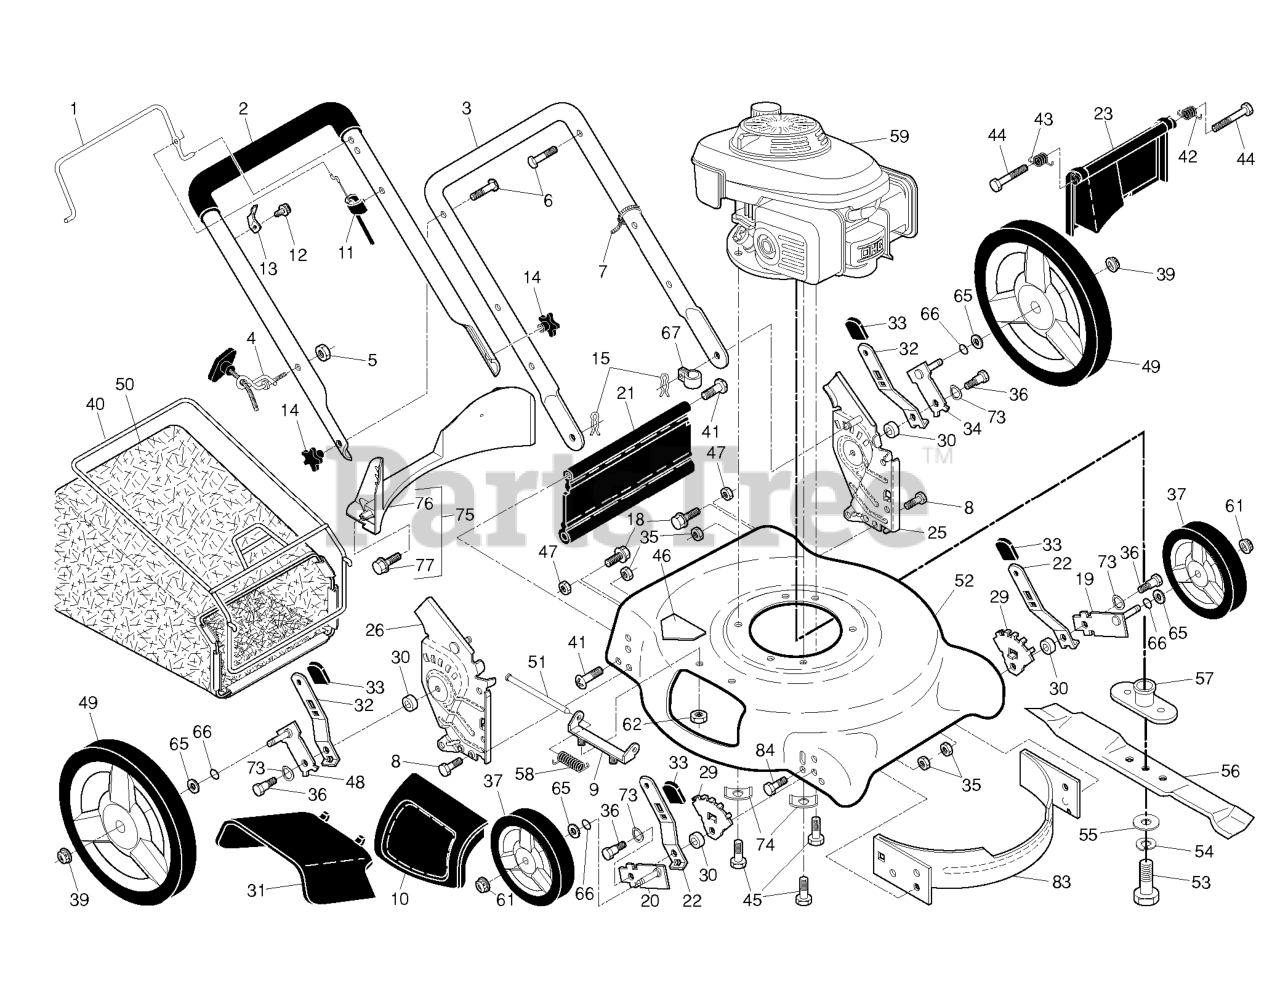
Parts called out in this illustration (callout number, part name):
1	BAIL.MZR.STD.ORANGE
2	UPPERHANDLE(INCLUDES FOAMGRIP)
3	HANDLE.LOWER.GREY
4	RB GUIDE.ROPE.STD.BLK.ZIN WSL
5	NUT
6	BOLT, HANDLE 5/16-18X1.75
7	TIE GUIDE
8	BOLT.FIN.HEX.5/16-18X3/4
9	BRACKET.ASM.HOUSING.EZ.MUL
10	RP DOOR.MULCH.21".REAR.PUSH.GR
11	CABLE.ENGINE.ZONE.CONTROL
13	BRACKET.UPSTOP.RT
14	KNOB.HANDLE.PLASTIC.STAR.BLACK
15	HAIRPIN COTTER
18	SCREW 1/4X20
19	AXLE ARM ASSY FRONT LH
20	AXLE ARM ASSY FRONT RH
21	RP_KIT.SKIRT.21 DOMED.W/LIP
22	SELECTOR SPRING, FRONT
23	REAR DOOR ASSY
25	RP BRKT.ASM.HAND.HW.21.LT.ORNG
26	RP BRKT.ASM.HAND.HW.21RT.ORNG
29	WHEEL ADJ BRACKET FRONT
30	SPACER.HEIGHT.ADJUSTER
31	DEFLECTOR.CLIPPING.21.GREY
32	SPRING.SEL.EXT.21.DOMED.12/14
34	AXLE ARM ASSY REAR LH
35	NUT.FLANGE.HEX.5/16X18.BLACK
36	SHOULDER BOLT 5/16-18
37	WHEEL & TIRES ASSY, FRONT
39	NUT.HEX.FLANGE.3/8-16.LOCKNUT
40	FRAME.BAG.21.REAR.DOMED.PUSH
41	HINGE SCREW
42	SPRING.LH.22.REAR.DOOR.EZ.EMPT
43	SPRING.RH.22.REAR.DOOR.EZ.
45	BOLT 3/8-16X1-1/8
46	DANGER DECAL
47	NUT.LOCK.5/16-18
48	AXLE ARM ASSY REAR RH
49	WHEEL ASSY
50	GBAG.2323247.SILVER
51	ROD.HINGE.COMBI-C
52	HOUSING.21.M/C.DOME.ORANGE
53	SCREW, HEX HD 3/8-24 X 1-3/8
54	LOCKWASHER
55	WASHER,HARDEN
56	BLADE.21.PUSH/RWGD/FWGD
57	ADAPTER.BLADE.W/KEY.25MM.CE
58	TORSION SPRING
61	NUT.HEX.FLANGE.3/8-16.LO(3 2)
62	LOCKNUT.NYLOC.1/4-20
65	WASHER.FLAT.1/2
66	O-RING..070X.487.NEOPRENE
67	CLIP.CABLE.BLK
73	WASHER.CURVED.CYLINDRICAL
74	WASHER.ENGINE.BZP
75	KIT.BAFFLE.REAR.PLASTIC.21.RD
76	BAFFLE.REAR.PLASTIC.21.RD.ECON
77	SCREW.HX.13X.750
83	BAFFLE.FRONT.21.DOME.US
84	BOLT.5/16HEX.WHS.HD
